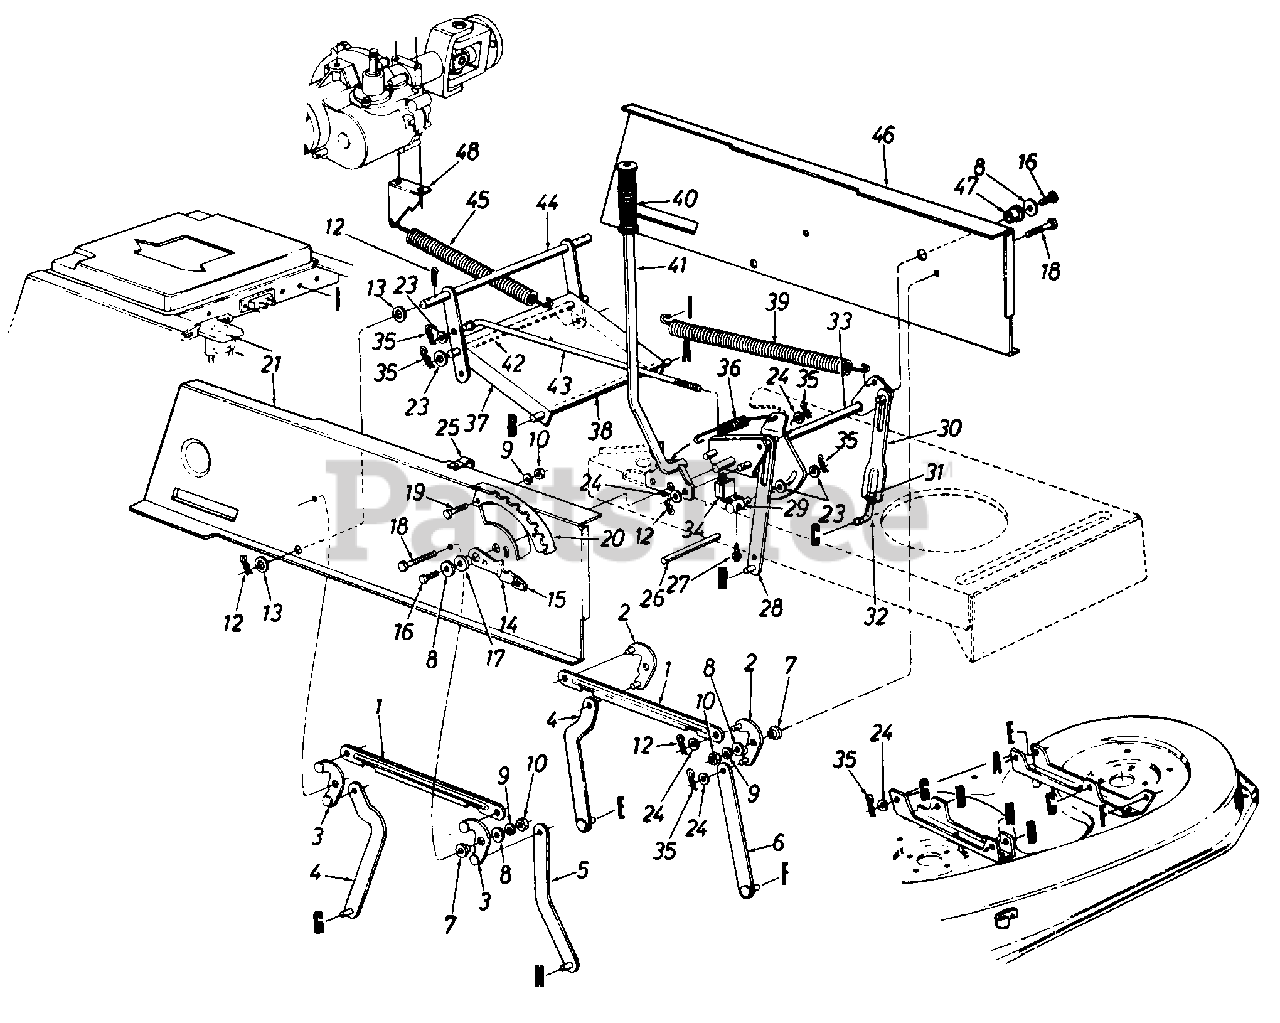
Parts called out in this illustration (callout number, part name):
1	Connecting Rod
2	Pivot Link Ass'y. L.H.
3	Pivot Link Ass'y. R.H.
7	Shld. Spacer .3/8" I.D.
8	Fl-Wash. .344" I.D. x 1.125"
9	L-Wash. 5/16" I.D.
10	Hex Nut 5/16-18 Thd.
12	Cotter Pin 1/8" Dia.
13	Fl-Wash. .635" I.D. x 1.0" O.D.
14	Deck Lift Down Stop
15	Knob
16	Hex Wash. TT-Tap Scr. 5/16-18 x .75" Lg.
17	Flange Brg. .63" I.D.
18	Hex Wash. TT-Tap Scr. 5/16-18 x.875" Lg.
19	Hex Bolt 5/16-18 x .75" Lg.
20	Index Brkt.
21	Upper Frame R.H.
23	Fl-Wash. .385" I.D. x .87" O.D.
24	Fl-Wash. .531" I.D. x .93" O.D.
25	Clamp
26	Running Board Rod
27	Truss Mach. Scr. #10 x .5" Lg.
31	Hex Nut 1/2-20 Thd. (Grade 5)
32	Lift Link Adjuster
33	Lift Shaft Ass'y.
34	Safety Switch (Deck)
35	Inter. Cotter Pin 3/8" Dia.
36	Extension Spring
37	Stabilizer Bracket
38	Shaft 1/2" Dia. x 10.28" Lg.
39	Extension Spring
40	Grip
41	Deck Lift Handle Ass'y.
42	Shaft 3/8" Dia. x 9.34" Lg.
43	Disengagement Rod
44	Stabilizer Shaft Ass'y.
45	Extension Spring 7 58" Lg.
46	Upper Frame L.H.
47	Flange Brg. .632" I.D.
48	Spring Retainer Brkt.
